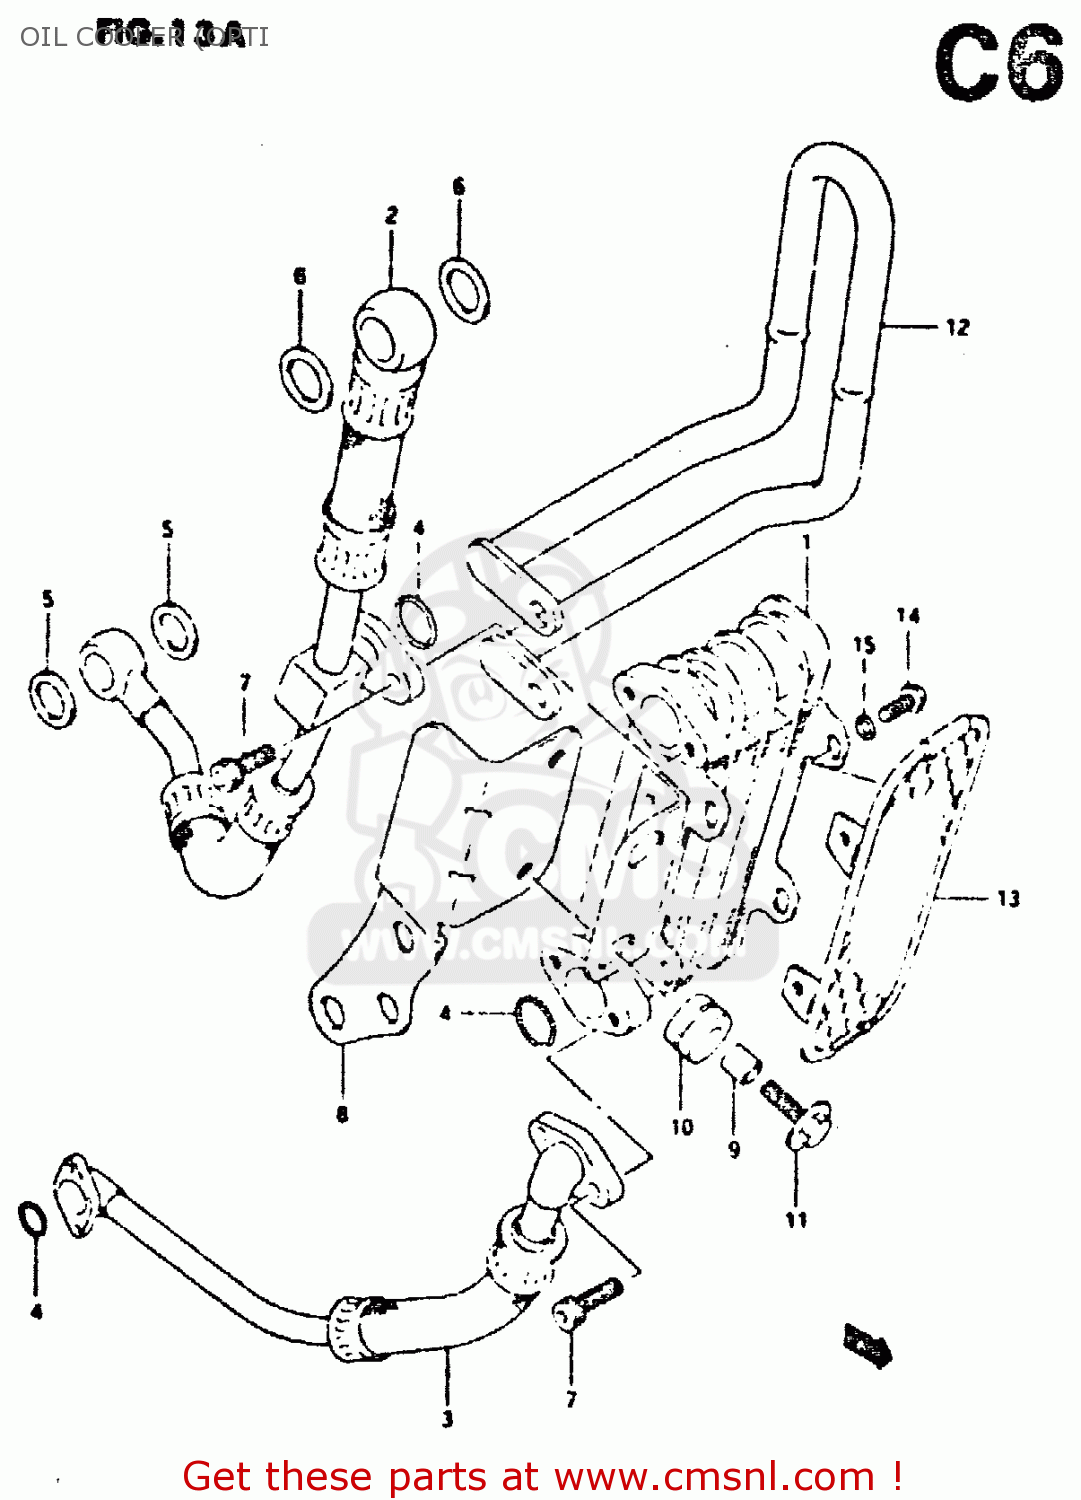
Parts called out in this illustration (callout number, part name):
1	COOLER ASSY,OIL
2	HOSE,OIL COOLER UPR
3	HOSE,OIL COOLER LWR
4	O RING(D:2.4,ID:12.3)
5	GASKET(12X17X1) (NAS)
6	GASKET(16X22X2) (NAS)
7	BOLT
8	BRACKET,OIL COOLER
9	SPACER (6.8X10X10)
10	CUSHION
11	BOLT 6X20
12	GUARD,OIL COOLER
13	BUMPER,OIL COOLER
14	BOLT
15	WASHER,LOCK
16	CLIP
17	CLAMP
18	PLUG(10X12)
19	GASKET(10X14X3.6) (NAS)
